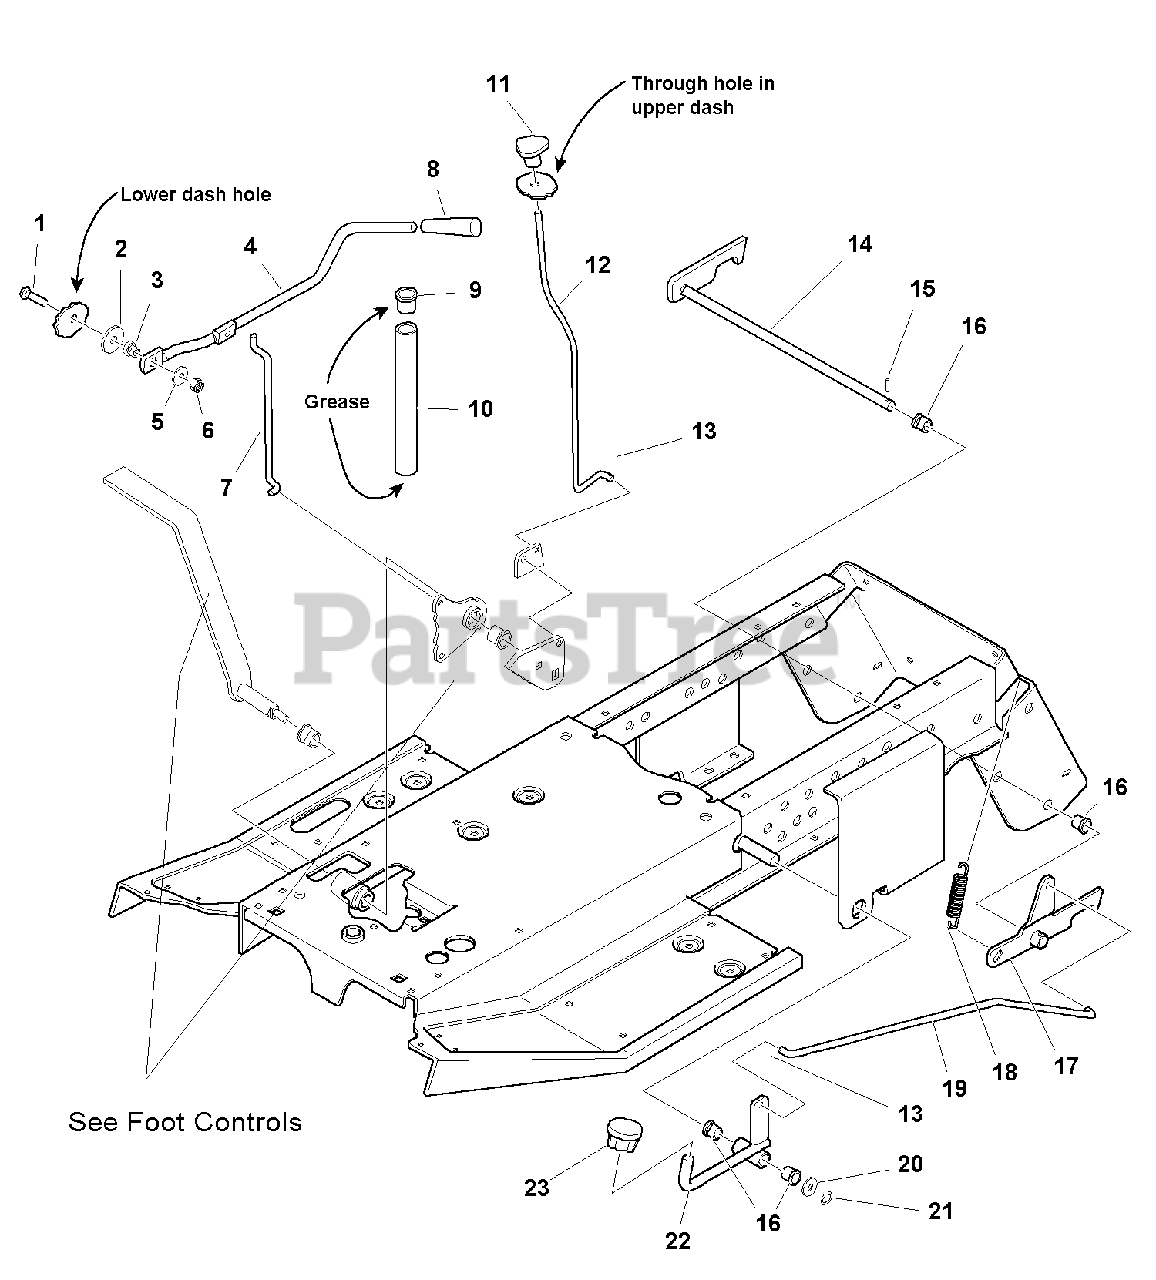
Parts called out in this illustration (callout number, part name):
1	CARRIAGE BOLT, 5/16-18 x 1-1/4
2	WASHER, 3/8
4	ROD, E-Coat Lift Handle, 13.23 Long
5	WASHER, 5/16
6	NUT, Hex Lock ESNA Light, 5/16-18
7	ROD, Link Lift Upper
8	KNOB, Lift Rod, Black
9	BUSHING, Nylon
10	TUBE, Shift, 8.60 Long
11	KNOB, 3 Sided Soft
12	ROD, 15.3 Long Parking Brake
13	PIN, Cotter, 1/16 x 3/4
14	ROD & LATCH ASSEMBLY, R H
15	PIN, Spring, 1/8 x 3/4
17	LATCH & SPACER ASSEMBLY, L H
18	SPRING, Extension
19	ROD, 22.31 Long Latch, Yellow
20	WASHER, Flat
21	RING-E, Return Extension
22	LEVER & ROD ASSEMBLY, Hopper Open
